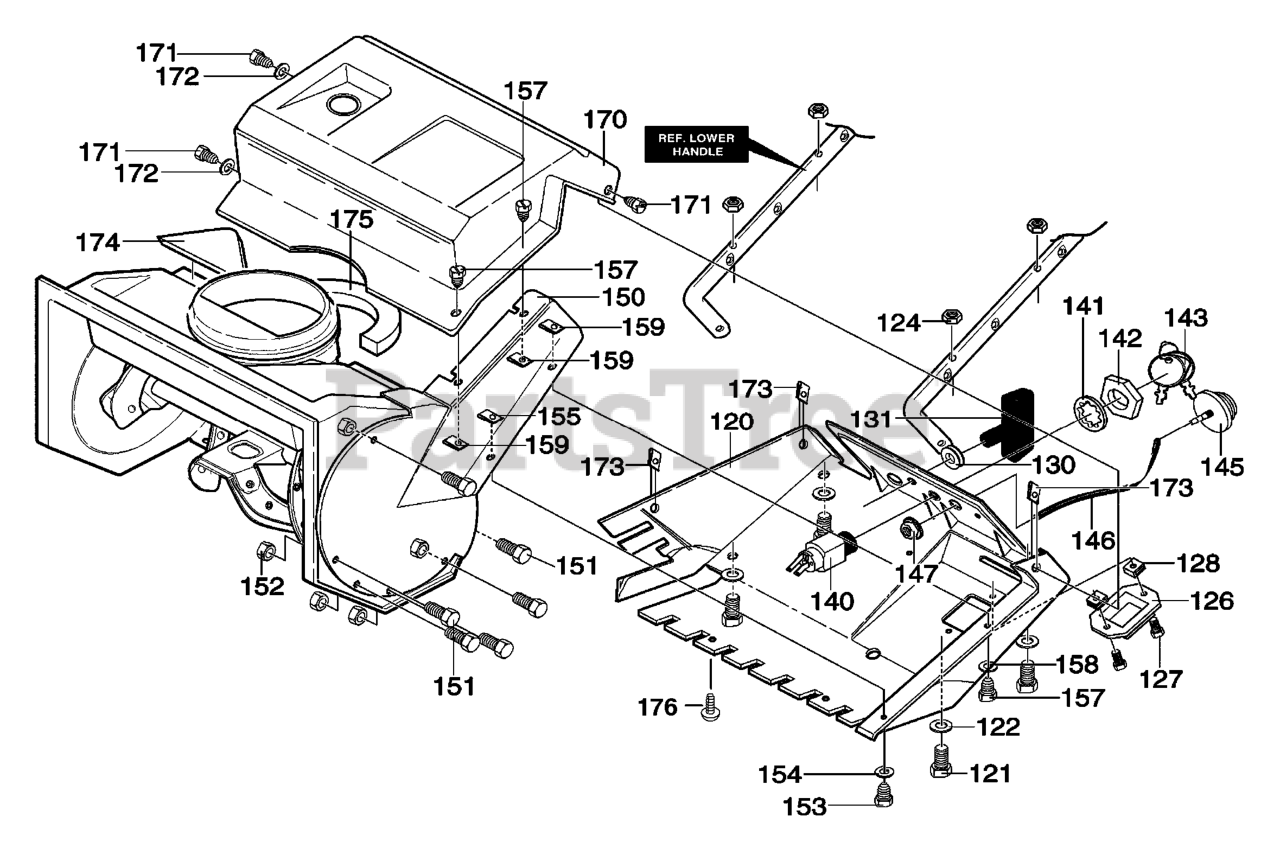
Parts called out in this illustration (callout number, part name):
120	COVER, BOTTOM
121	SCREW, 1/4-20X1.25
122	WASHER, FLAT .281X.63X.065
124	NUT, 1/4-20 YZ
126	COVER, CARB
127	SCREW, 1/4-14X.75
128	NUT, 1/4-10 SPEED J TYPE
130	GROMMET & WASHER, ROPE GUIDE
131	KNOB, STAND TEE
140	SWITCH, IGNITION
141	WASHER
142	NUT, 5/8-32 ACC
143	2 KEYS & RING
145	PRIMER, ENGINE
146	HOSE, PRIMER
147	KEPS NUT, 1/4-20
150	COVER, BELT
151	SCREW, 10-24X.50
152	NUT, #10-24
153	SCREW, 1/4-20X.50
154	WASHER, FLAT .281X.63X.065
155	NUT, 1/4-20 TINN
157	SCREW, 1/4-14X.75
158	WASHER, FLAT .281X.63X.065
159	NUT, 1/4-20 SPEED J TYPE
170	COVER, TOP
171	SCREW, 1/4-14X.75
172	WASHER, FLAT .281X.63X.065
173	NUT, 1/4-10 SPEED J TYPE
174	SEAL, FOAM
175	SEAL, STRIP CHUTE & GAS SEAL
176	SCREW 10-14 x 0.63
